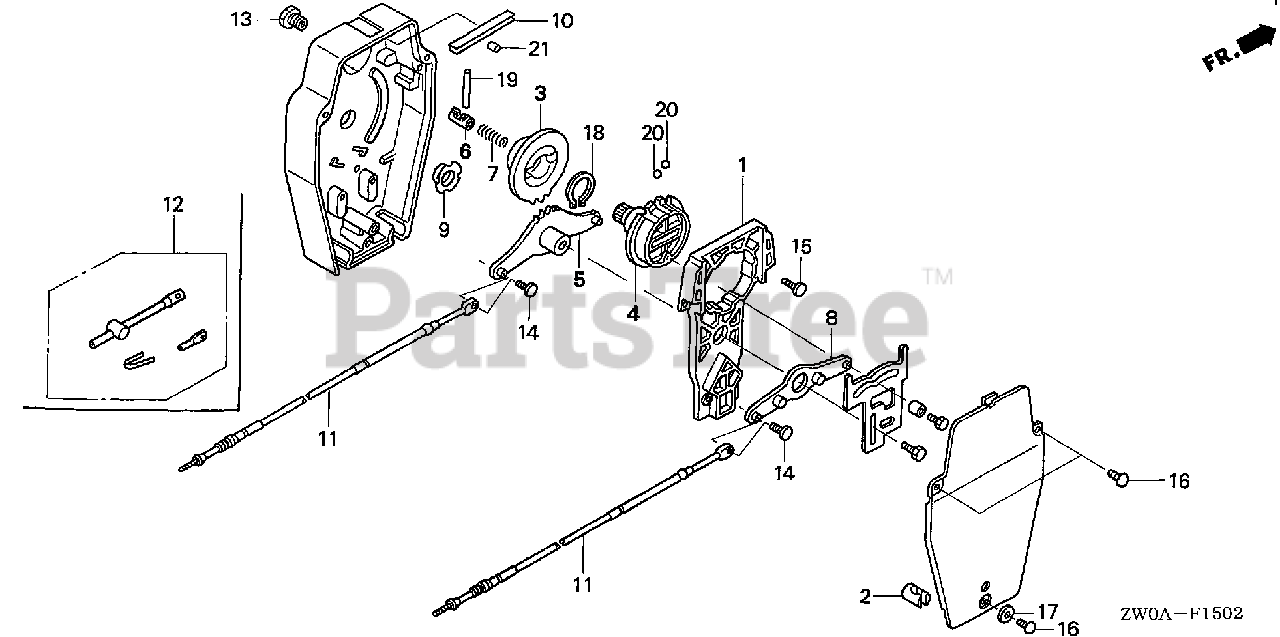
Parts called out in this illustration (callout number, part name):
1	FRAME ASSY., REMOTE CONTROL
3	WHEEL, CONTROL
4	SHAFT, HANDLE
5	ARM ASSY., SHIFT LINK
6	SHAFT, GEARSHIFT
7	SPRING, GEARSHIFT
8	ARM ASSY., THROTTLE LINK
11	CABLE, REMOTE CONTROL (10')
11	CABLE, REMOTE CONTROL (11')
11	CABLE, REMOTE CONTROL (12')
11	CABLE, REMOTE CONTROL (13')
11	CABLE, REMOTE CONTROL (14')
11	CABLE, REMOTE CONTROL (15')
11	CABLE, REMOTE CONTROL (16')
11	CABLE, REMOTE CONTROL (17')
11	CABLE, REMOTE CONTROL (18')
11	CABLE, REMOTE CONTROL (19')
11	CABLE, REMOTE CONTROL (20')
12	ADAPTER, REMOCON CABLE
14	SCREW (8-32X3/8)
15	SCREW (10-32X5/8)
16	SCREW (10-32X5/8)
18	CIRCLIP (OUTER)
19	PIN, GEARSHIFT
20	BALL, STEEL
21	ROLLER, SHIFT CLICK
